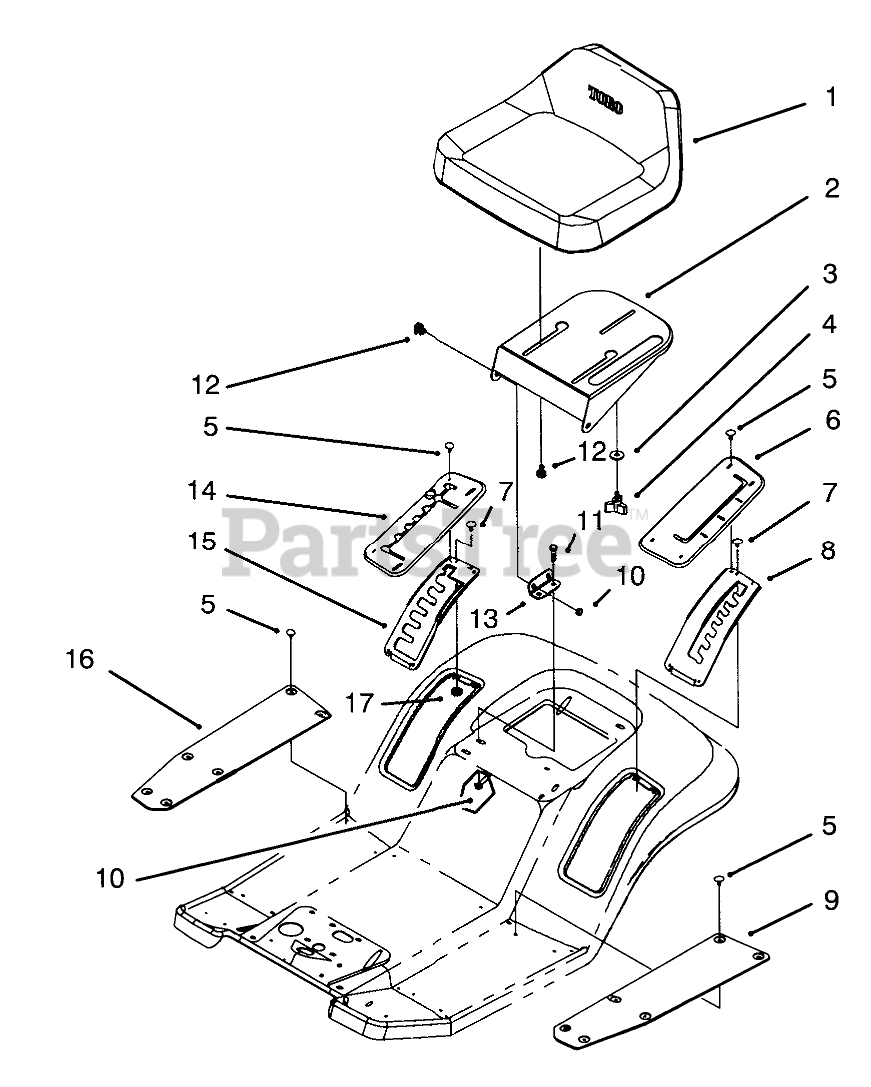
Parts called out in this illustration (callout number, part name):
1	SEAT
2	Support-Seat
3	WASHER-PIVOT
5	FASTENER-PANEL
6	COVER-HOC
7	RIVET-POP
8	Gate-H.O.C.
9	MAT-FOOT, LH
10	NUT-LOCK, NI
11	SCREW-HH
12	BOLT-SHOULDER
13	Bracket-Seat Hinge
14	COVER-GATE, SHIFT
15	Gate-Shift
16	MAT-FOOT, RH
17	WASHER-FLAT
